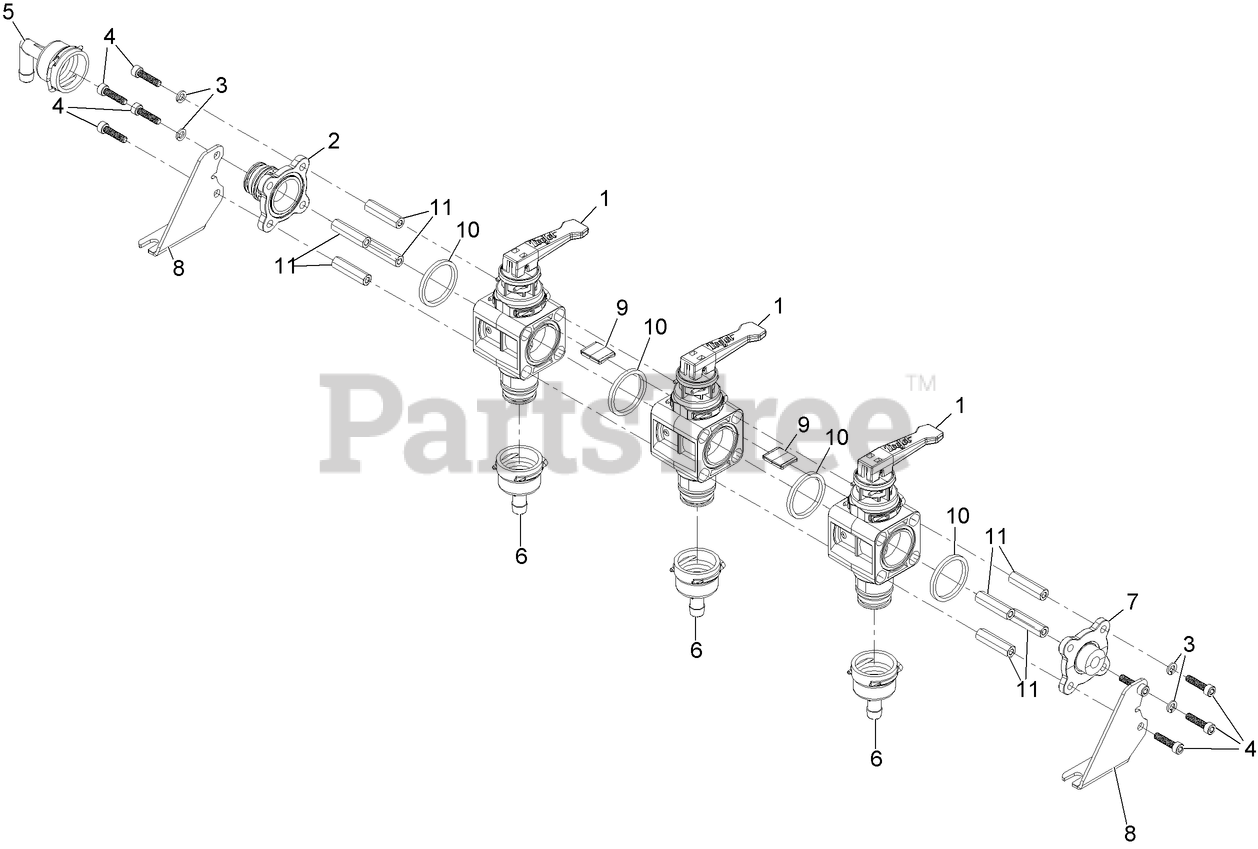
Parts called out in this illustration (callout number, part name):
1	ASM-VALVE SECTION, GREY
2	ADAPTOR-MALE QC BOLTED FLANGED
3	WASHER
4	SCREW-HSCS 6 MM X 25.0 MM SS
5	KIT-HOSE BARB, 1/2 90, QC
6	KIT-1/2 HB, STR, QC
8	BRKT-SPRAYER MANIFOLD
9	ALIGNMENT PIECE
10	GASKET
11	M6X1 METRIC HEX STAND-OFF
